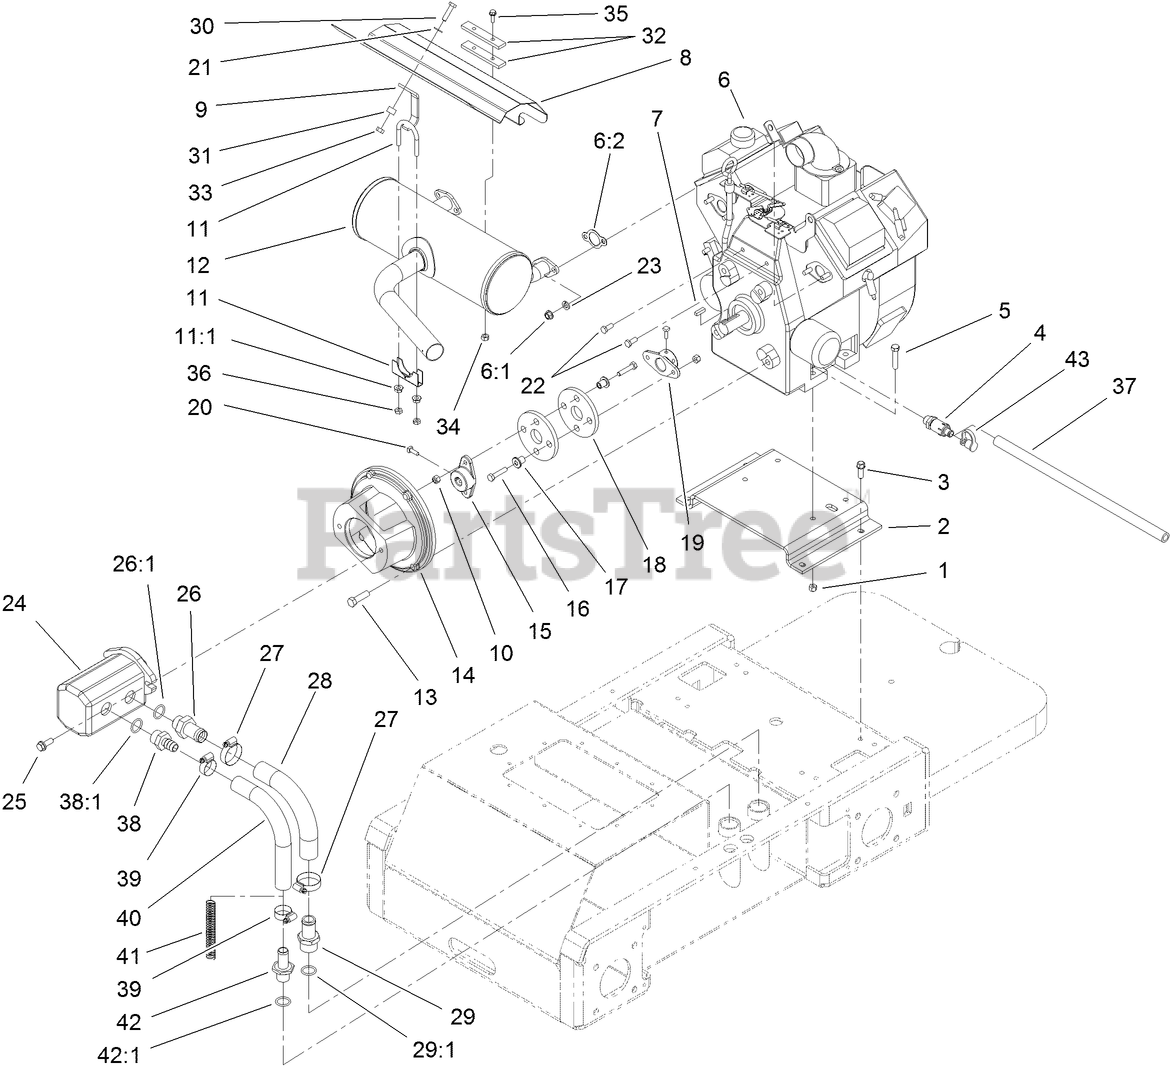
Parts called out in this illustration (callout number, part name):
1	NUT-LOCK, NI
2	MOUNT-ENGINE
3	SCREW-TAPTITE
4	VALVE-DRAIN, OIL
5	SCREW-HH
6	ENGINE-KOHLER, CH680S
6:1	NUT-HF
6:2	GASKET-EXHAUST
7	KEY-SQUARE
8	SHIELD-MUFFLER
9	SUPPORT-SHIELD
10	NUT-LOCK, NI
11	CLAMP
11:1	NUT-HF
12	Muffler
13	SCREW-HH
14	MOUNT-PUMP
15	HUB-PUMP
16	SCREW-HH
17	SPACER
18	COUPLING-RUBBER
19	HUB-ENGINE
20	SCREW-SQH
21	WASHER-PLAIN
22	SCREW-HH
23	WASHER-LOCK
24	HYD PUMP ASM
25	SCREW-HHF
26	FITTING
26:1	O-RING
28	HOSE-SUCTION, FORMED
29	FITTING-STR
29:1	O-RING
30	SCREW-HH
31	SPACER
32	SPACER-BAR
33	NUT-LOCK, CONE
34	NUT-LOCK, CONE
35	SCREW-HHF
36	NUT-JAM
38	FITTING-STRAIGHT
38:1	O-RING
39	CLAMP-HOSE
40	HOSE-SUCTION, HYD
41	Spring-Compression
42	FITTING-HOSE, BARBED
42:1	O-RING
43	CAP-DUST
